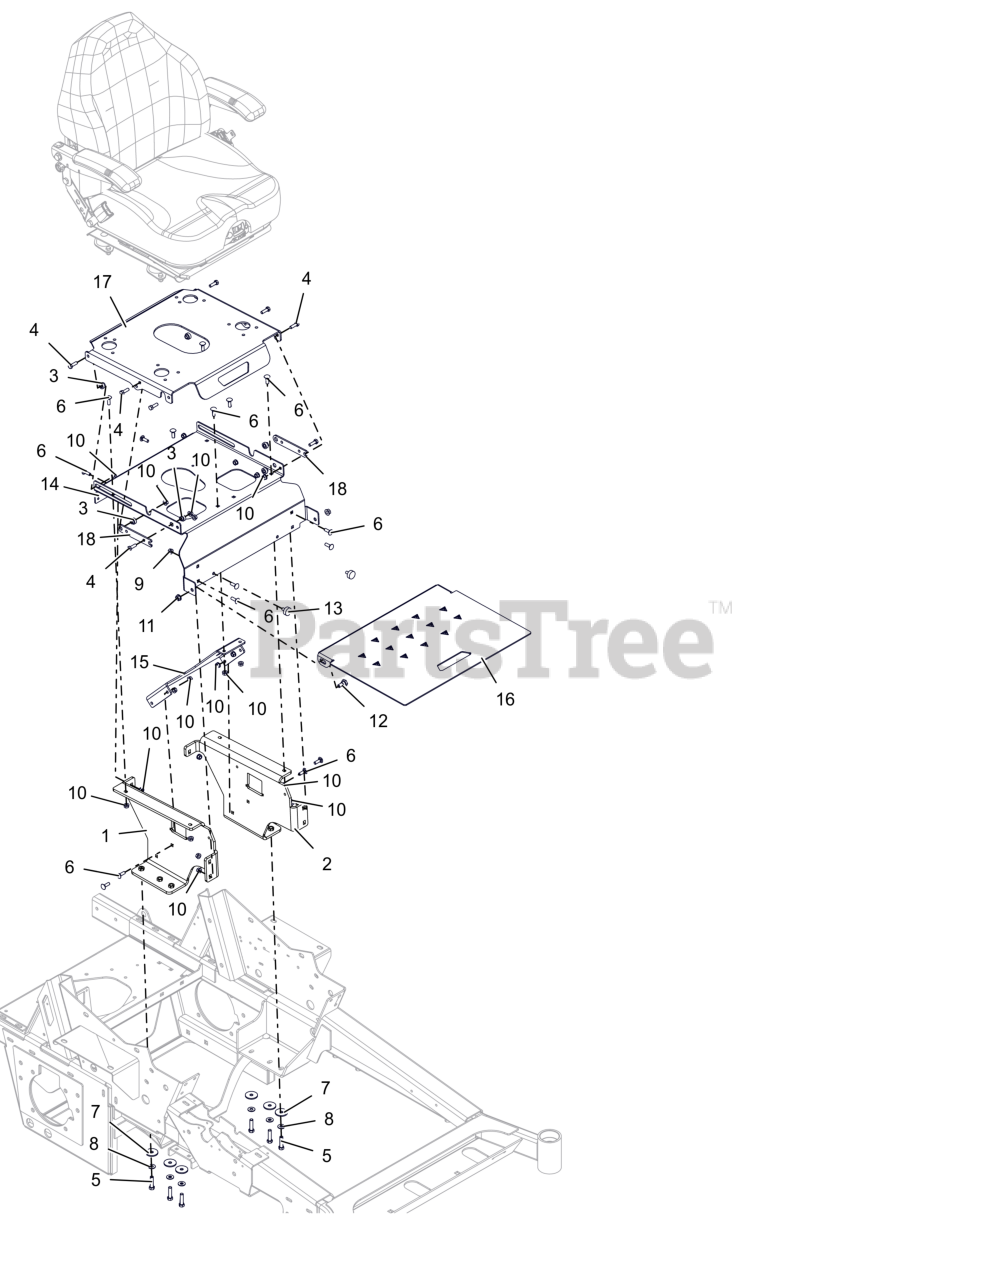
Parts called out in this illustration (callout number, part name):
1	BRKT- SEATBOX RH SUPPORT - RED
2	BRKT- SEATBOX LH SUPPORT
3	SPCR, BRG .315X.500X.481X.281
4	BLT, HEX .31-18X1.00 G8 ZCC
5	BLT, HEX 0.375-16X1.5 GR8 ZCC
6	BLT,RHSN .31-18X1.00 G5 ZCC
7	WSHR, FLT .380X1.50X.125 ZCC
8	WSHR, HDND 0.375X0.875X0.064 ZCC
9	NUT,SPNLK-FLG .31-18 G5 ZCC
10	NUT,LK-CTR-FLG .31-18 GF ZCC
11	NUT-LK-CTR-FLG .375-16 GF ZCC
12	BLT,SHLDR EP .38-16X.30 HEX YZ
13	BUMPER, RUBBER
14	BRKT- SEATBOX ISOLATOR MTG
15	BRACE- CROSS
16	FOOTREST
17	BRKT, SEATBOX TILT UP (RED)
18	BRKT- SEATBOX TILT UP PIVOT
